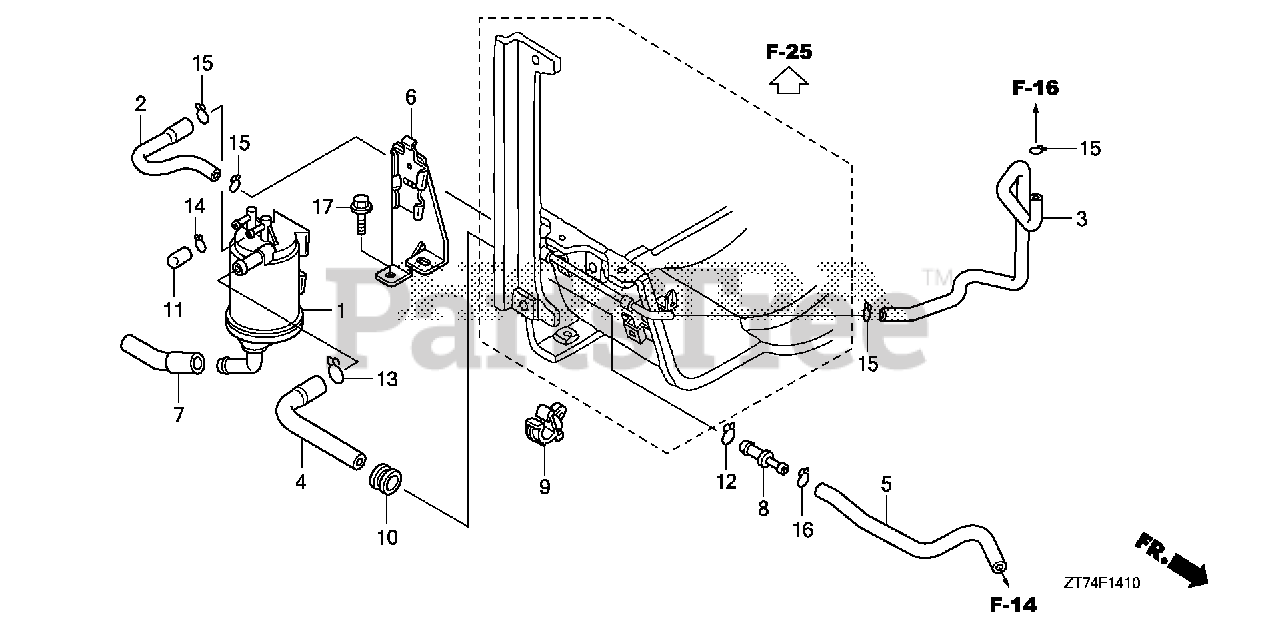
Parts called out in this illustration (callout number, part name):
1	CANISTER ASSY.
2	TUBE A, CANISTER CHARGE
3	TUBE B, CANISTER CHARGE
4	TUBE A, CANISTER PURGE
5	TUBE B, CANISTER PURGE
6	BRACKET, CANISTER
7	TUBE, CANISTER DRAIN
8	JOINT, BREATHER TUBE
9	CLAMP, WIRE
10	GROMMET, FENDER
11	CAP, SEALING
12	CLIP, TUBE (B12.5)
13	CLIP, TUBE
14	CLIP, TUBE (B7)
15	CLIP, TUBE (B8)
16	CLIP, TUBE (B10)
17	BOLT, FLANGE (6X10)
